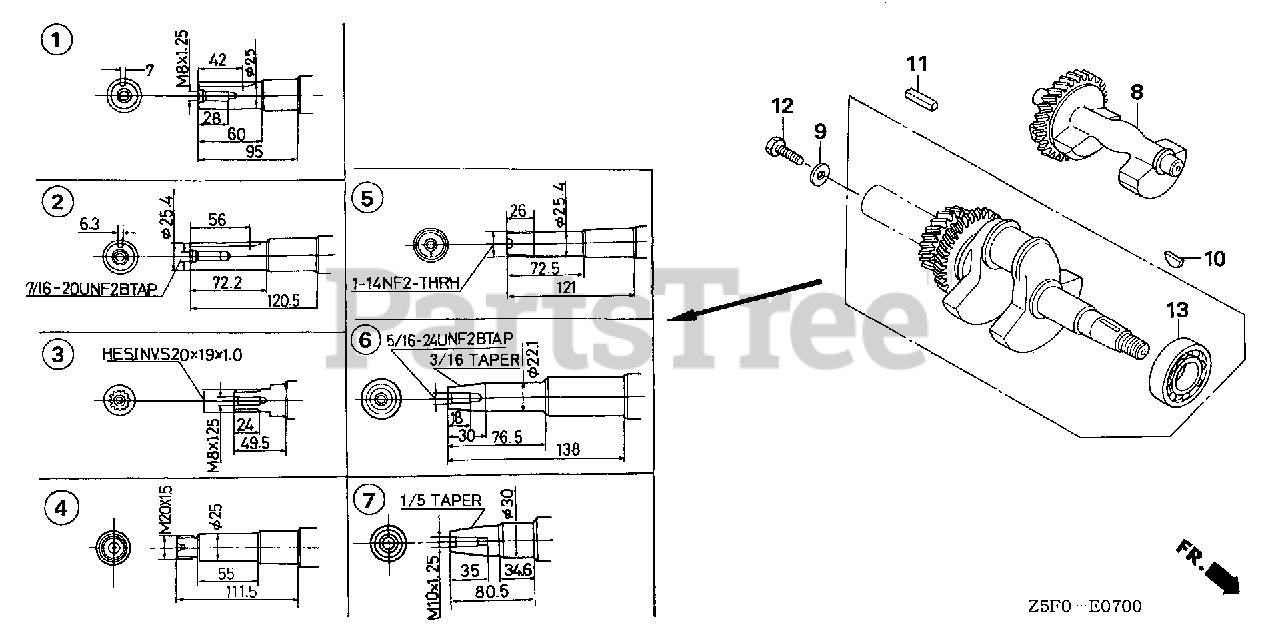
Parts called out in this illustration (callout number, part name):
3	CRANKSHAFT
8	WEIGHT, BALANCER
10	KEY, SPECIAL WOODRUFF (25X18)
13	BEARING, RADIAL BALL (6206)
